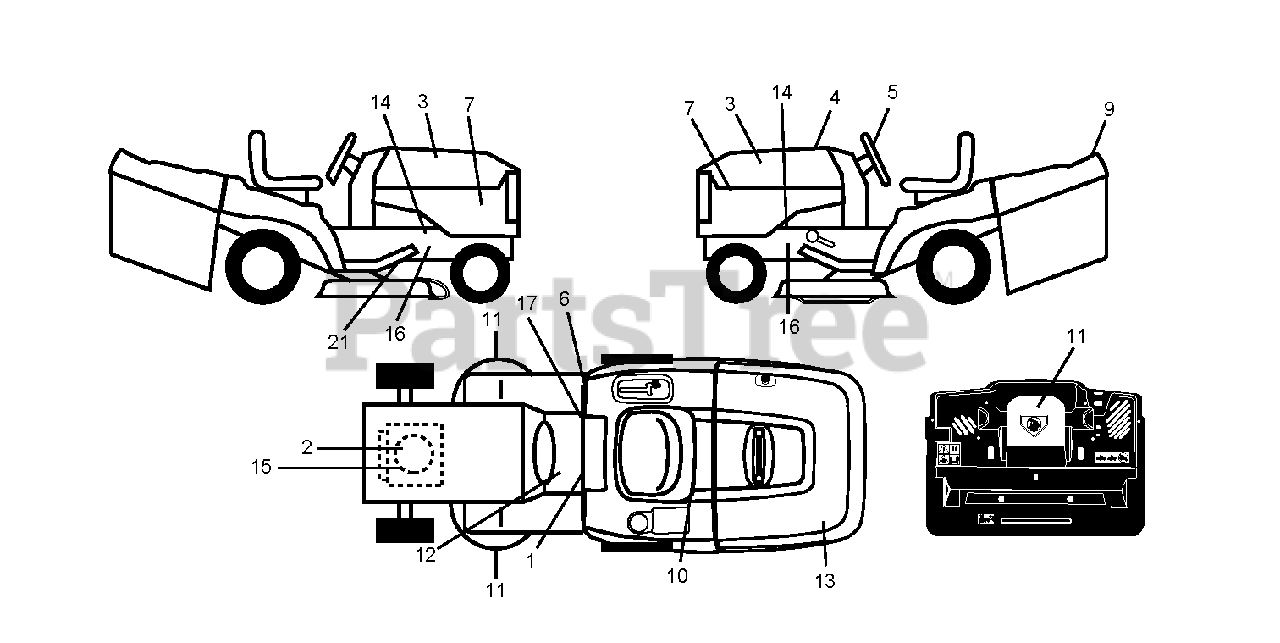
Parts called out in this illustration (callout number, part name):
8	KNOB.SKID.PLATE
10	DECAL BTRY SYMBOLS
11	DECAL.INTERNATIONL.CUTFINGER
17	DECAL PARK BRAKE
